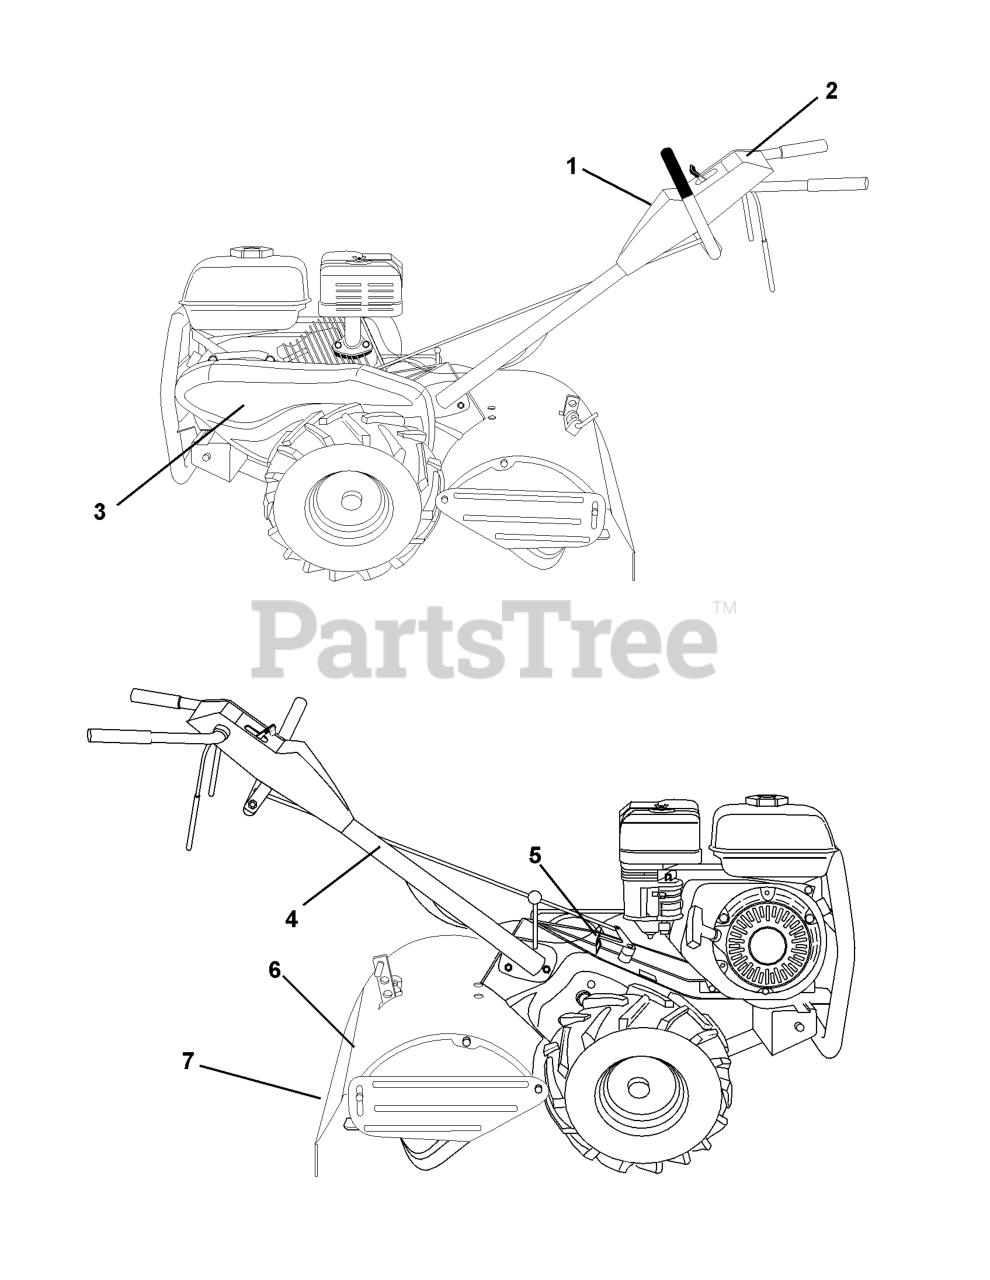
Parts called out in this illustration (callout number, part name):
1	DECAL, LOGO
2	LOGO DECAL
3	Decal, Logo
4	DECAL TI (2 2)
5	DECAL.SHIFT.INDICATOR.TILLER
6	DECAL -CAUTION
7	DECAL TI
